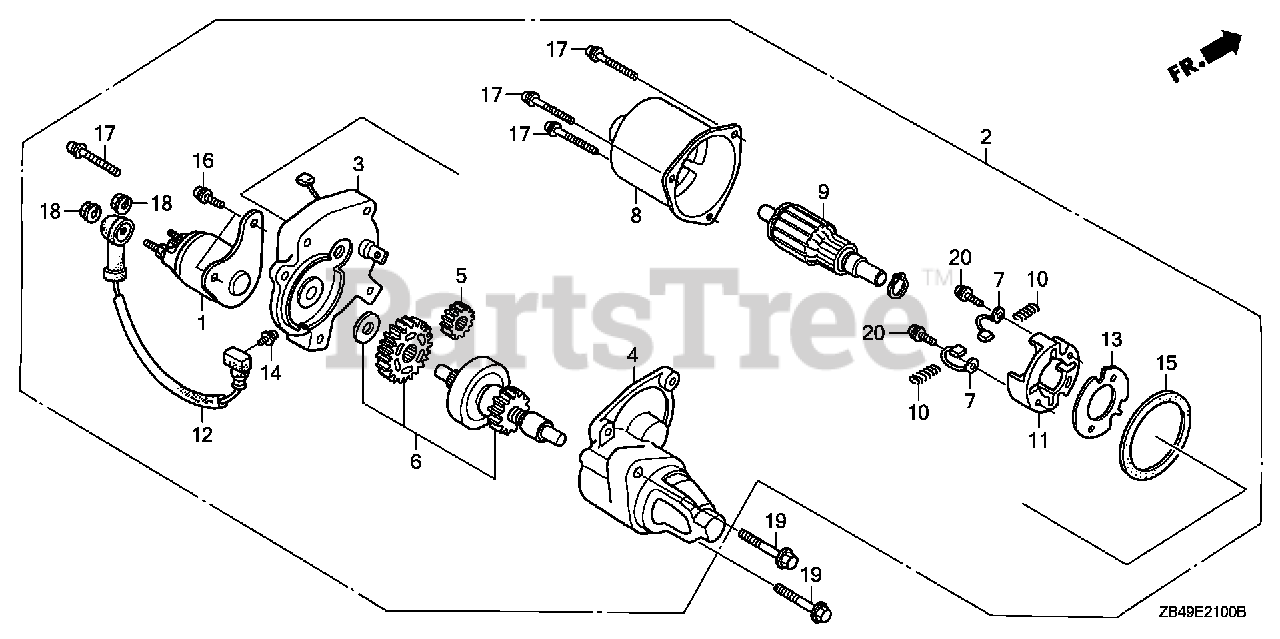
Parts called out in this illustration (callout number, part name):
1	CONTACTOR ASSY.
2	STARTER MOTOR UNIT
3	BRACKET, CENTER
4	BRACKET, FR.
5	GEAR, DRIVE PINION
6	CLUTCH, OVERRUNNING
10	SPRING, BRUSH RETURN
11	HOLDER, BRUSH
12	WIRE, WATER COVER
14	SCREW-WASHER (4X6)
16	BOLT-WASHER (5X14)
17	SCREW-WASHER (5X32)
18	NUT-WASHER (6MM)
19	BOLT, FLANGE (8X40)
20	STARTER MOTOR UNIT
